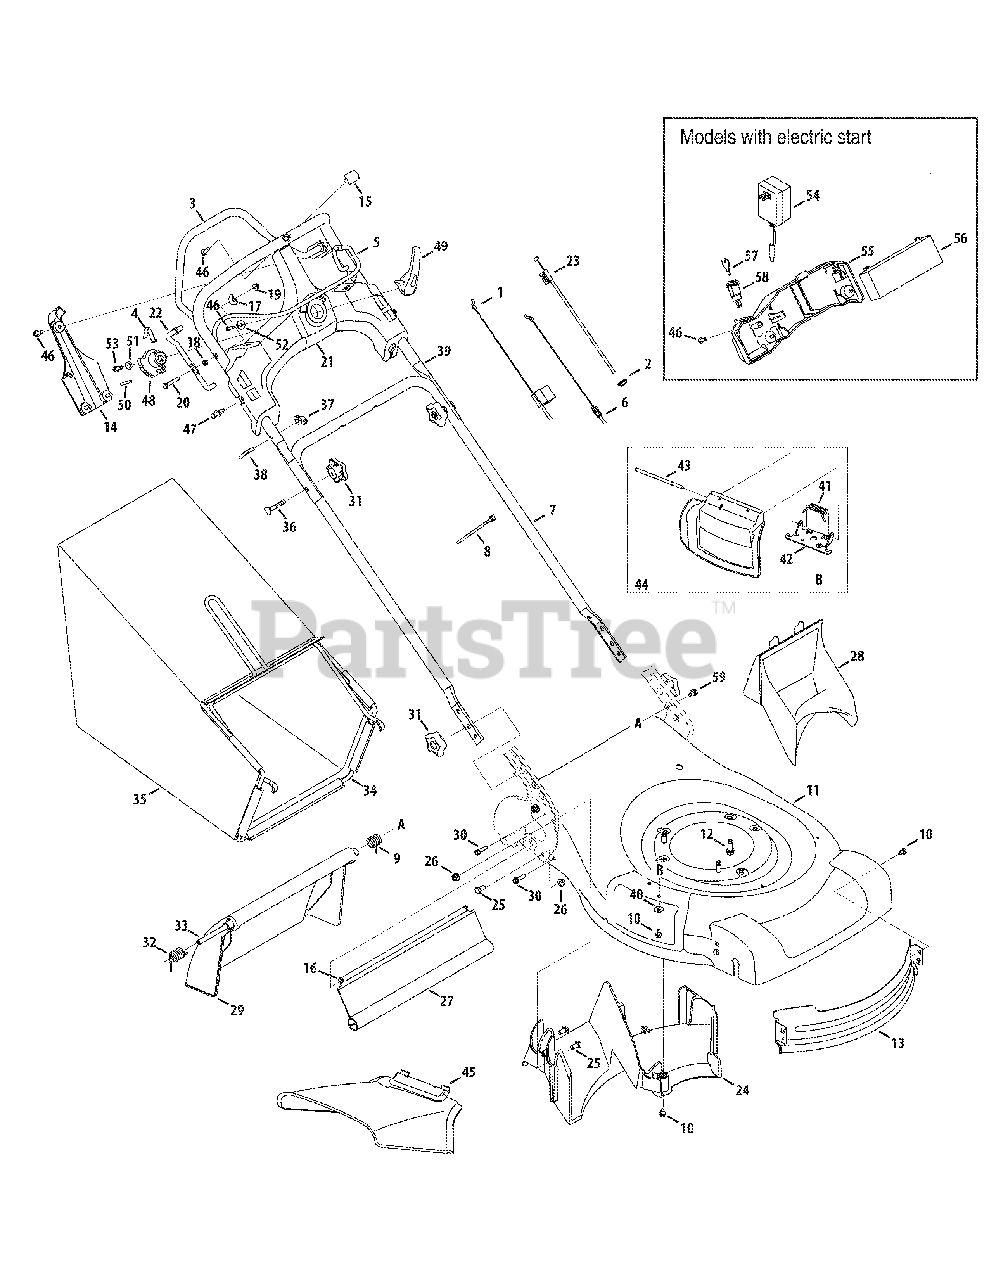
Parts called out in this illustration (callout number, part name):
1	Drive Cable
2	Rubber Grommet
3	Drive Control Ass'y
5	Blade Control Handle
6	Control Cable Snap-in 48.9" Lg.
9	Torsionl Spring LH
10	Hex Wash S-Tapp Scr 1/4-20 x .50
12	Hex Wash HD Tap Scr 3/8-16 x .88
13	Deck Baffle Kit
14	Variable Speed Contol Panel Cover
15	Variable Speed Contol Panel Cover
16	Screw, #10-16 x .50
17	Saddle Washer
18	L-Wash 1/4 ID
19	Flanged Lock Nut 1/4-20 Gr. F Nylon
20	Hex Cap Screw1/4-20 x 1.5" Lg.
21	Control Panel
22	Bail Pivot Rod - RH
22	Bail Pivot Rod LH
23	Variable Speed Cable
25	Screw, 5/16-18 x .625
26	Hex Flange L-Nut 5/16-18 Gr. F
28	Rear Mulching Plug
29	Rear Discharge Door
30	Hex Lock Screw 1/4-15 x 1.0
31	Knob - Star 5/16-18
32	Torsionl Spring RH
33	Door Pivot Rod
34	Grass Bag Frame
35	Grass Bag - Black
36	Carriage Bolt 5/16-18 x 2.0
38	Rope Guide Bolt
40	Cup. Wash. .265 ID x .75 OD x .062
41	Torsionl Spring
42	Chute Hinge
43	Hinge Pin
44	Complete Mulch Plug
45	Side Chute Deflector
46	Screw, 1/4-20 x .75
47	Rivet, plastic
48	4 Speed Actuator
49	Speed Selector Level
51	Washer
52	Flat Washer .250 x .750 x .119
53	Screw, 1/4-15 x .750
54	Battery Charger
55	Harness Assembly
56	Battery, 12V
57	Ignition Key
58	Key Switch
